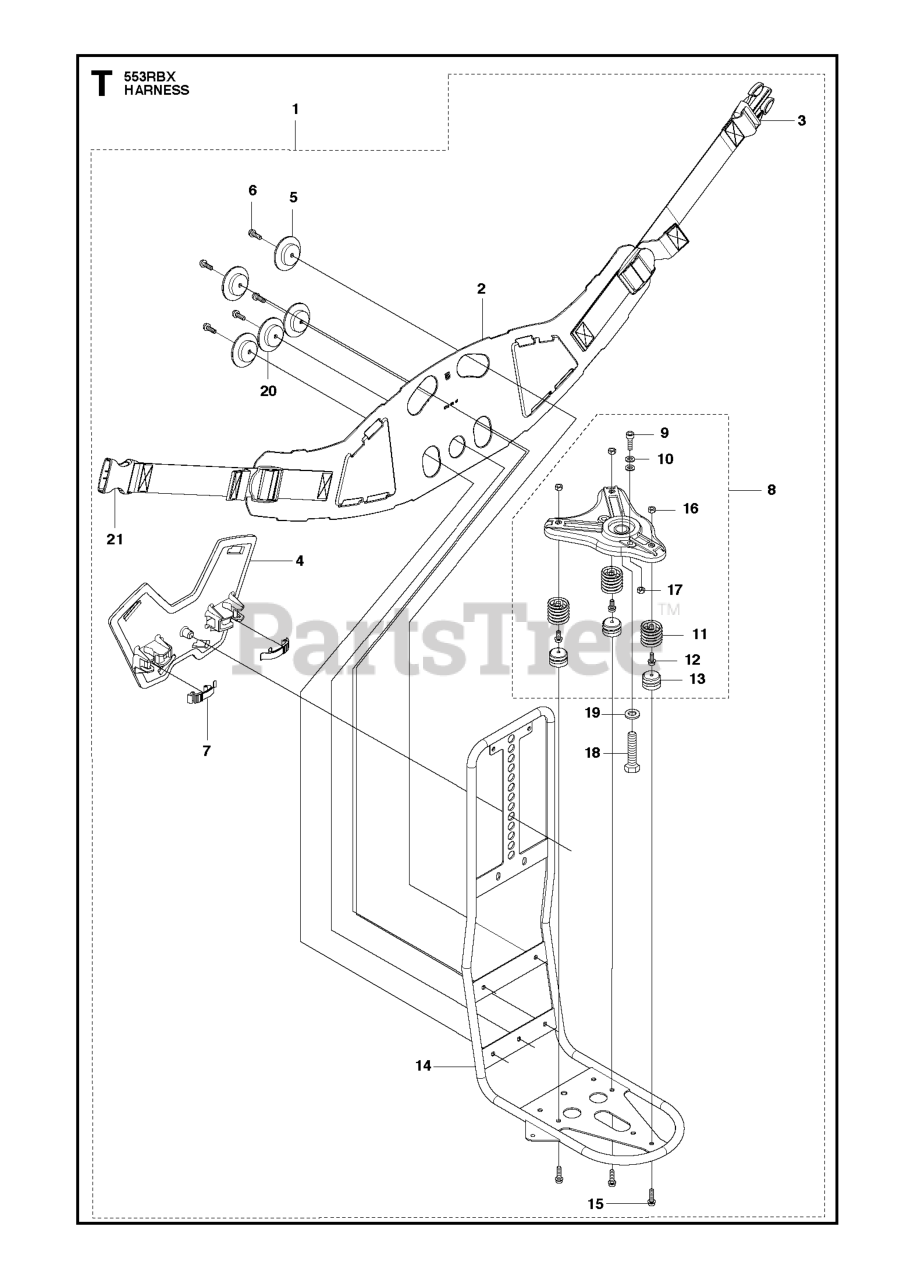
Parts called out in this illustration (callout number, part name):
3	BUCKLE, MALE
9	SCREW IHSCM
10	WASHER - M6
19	WASHER, M10 x 1.6
21	BUCKLE, FEMALE
